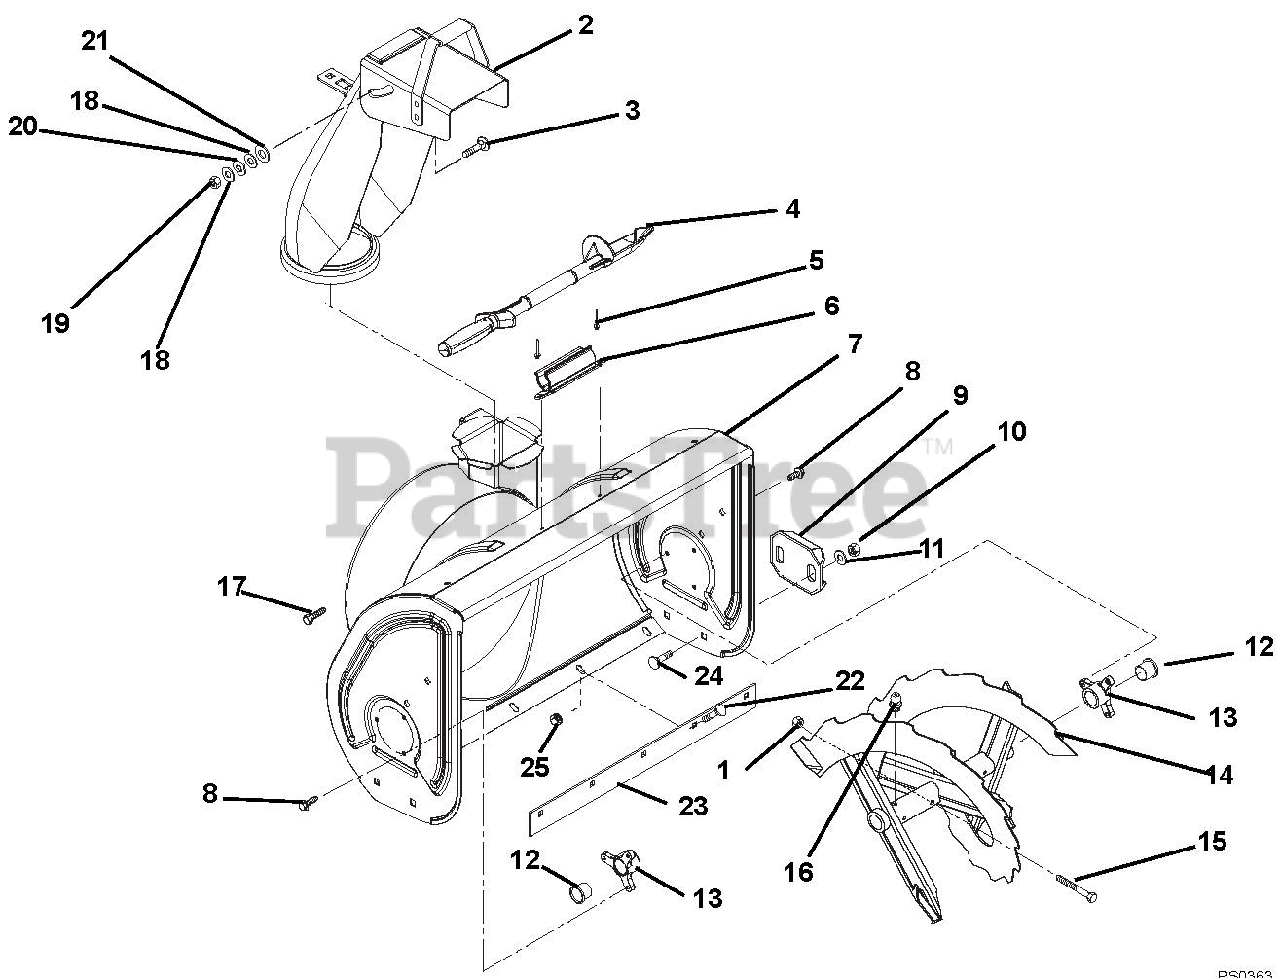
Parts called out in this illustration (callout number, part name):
1	@NUT-LK-CTR .25-20 YWZC
2	CHUTE, DISCHARGE W/CAP & DECAL
3	@BLT-RHDSSQNK .31-18X.75 G5YZ
4	DEVICE, SNOW CLEAN OUT
5	RVT-POP .187 YZ
6	MOUNT, SNOW CLEAN OUT
7	BLOWER HOUSING - 24"
7	BLOWER HOUSING - 20"
8	@SCR-TAP .25-20X.50 HWH TR YWZ
9	SKID SHOE, REVERSIBLE - ORANGE
10	@NUT-LK-CTR .38-16 YWZC
11	@WSHR-FL-STL.38X.875X.083 YWZC
12	BSHG-FLG SPLIT NYLINER .75"ID
13	BUSHING, RAKE SHAFT .75"
14	RAKE, 24" RH, BLK SERR W/ZERK
14	AUGER, 20" RH, BLK SERR W/ZERK
14	RAKE, 24" LH, BLK SERR W/ZERK
14	AUGER, LH 20", BLK SERR W/ZERK
15	SHEAR BOLT WITH NUT
16	ZERK,FITTING .25X.125 DRIVE IN
17	@SCR-TAP .31-18X.50 HWH TR YWZ
18	@WSHR-FL-STL.344X.688X.065YWZC
19	@NUT-LK-CTR .31-18 YWZC
20	WAVE WASHER .390X.655X.110
21	WSHR-FL-NY .375X.75X.060
22	@BLT-RHDSSQNK .31-18X.62 G5YZ
23	BLADE, SCRAPER - 24" COMPACT
23	BLADE, SCRAPER - 20" COMPACT
24	@BLT-RHDSSQNK .38-16X.75 G5YZ
25	@NUT-LK-TOP-FLG .31-18 YWZC
